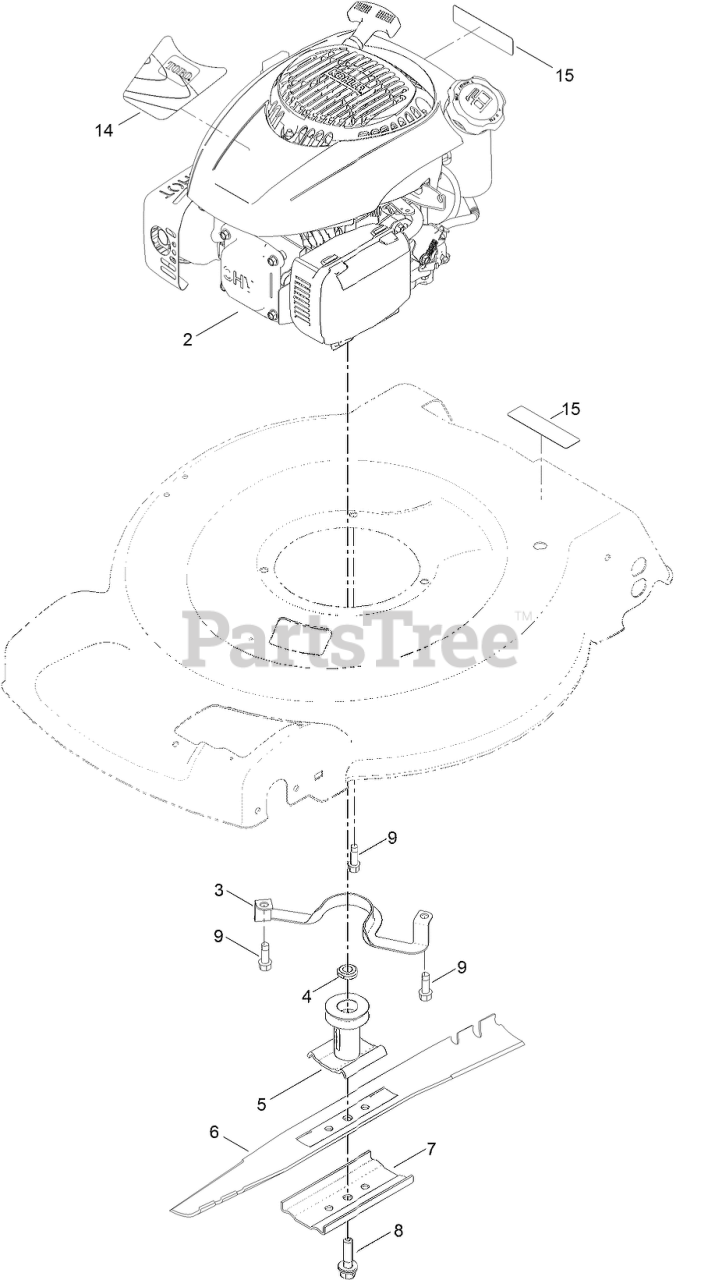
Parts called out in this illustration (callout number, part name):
3	GUIDE-BELT
4	SPACER-DRIVER
5	DRIVER-BLADE
6	BLADE-22 INCH
7	SUPPORT-BLADE
8	BOLT-BLADE
9	SCREW-TAPTITE
14	DECAL-SHROUD
15	DECAL-ARRESTER, SPARK
